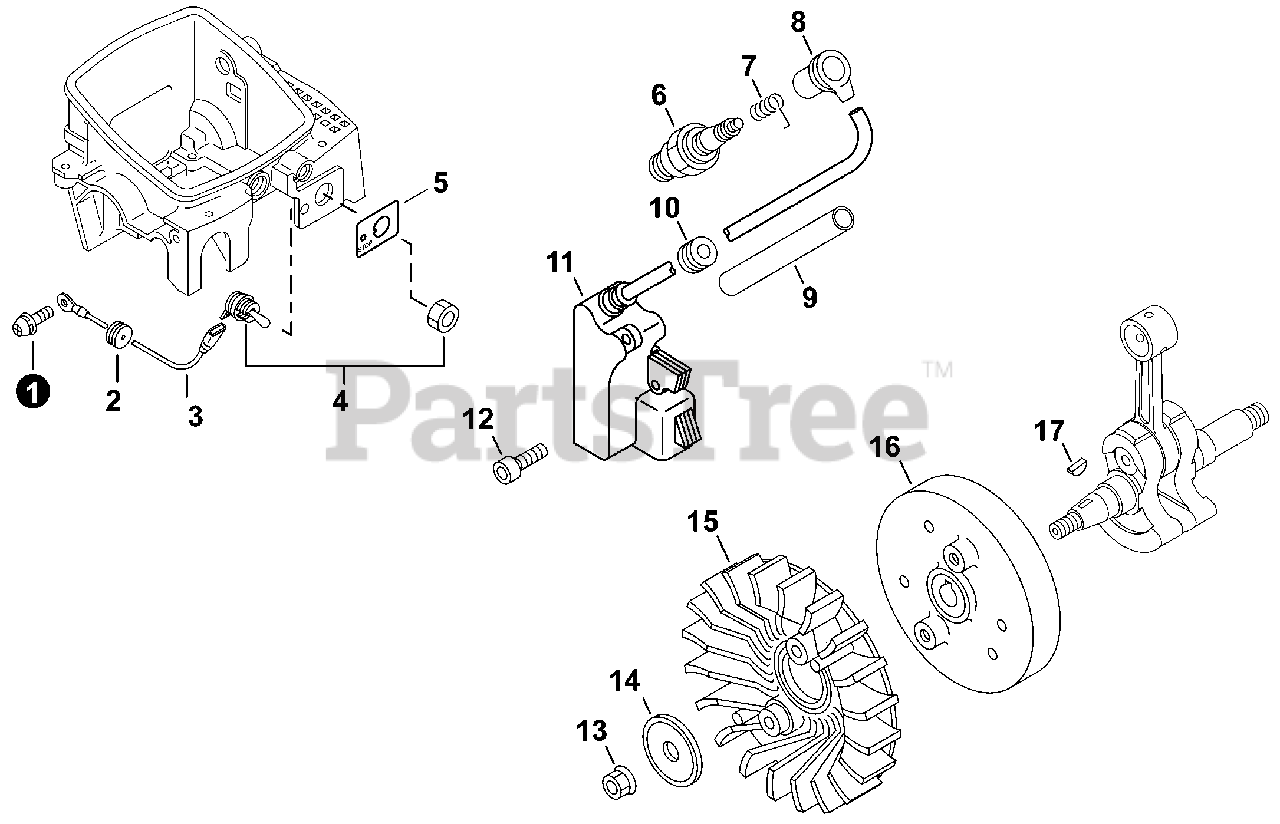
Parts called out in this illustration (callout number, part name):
1	SCREW 4x8
4	SWITCH, ON-OFF
5	LABEL - STOP
6	SPARK PLUG - BPM7A
7	TERMINAL, SPARK PLUG
8	CAP, SPARK PLUG
9	TUBE 7x8.6x45
11	COIL, IGNITION
12	BOLT 4x20
13	NUT, FLANGE M8x1.25
14	WASHER 8.2x31x0.8
15	FAN, COOLING
16	FLYWHEEL
17	KEY, WOODRUFF
